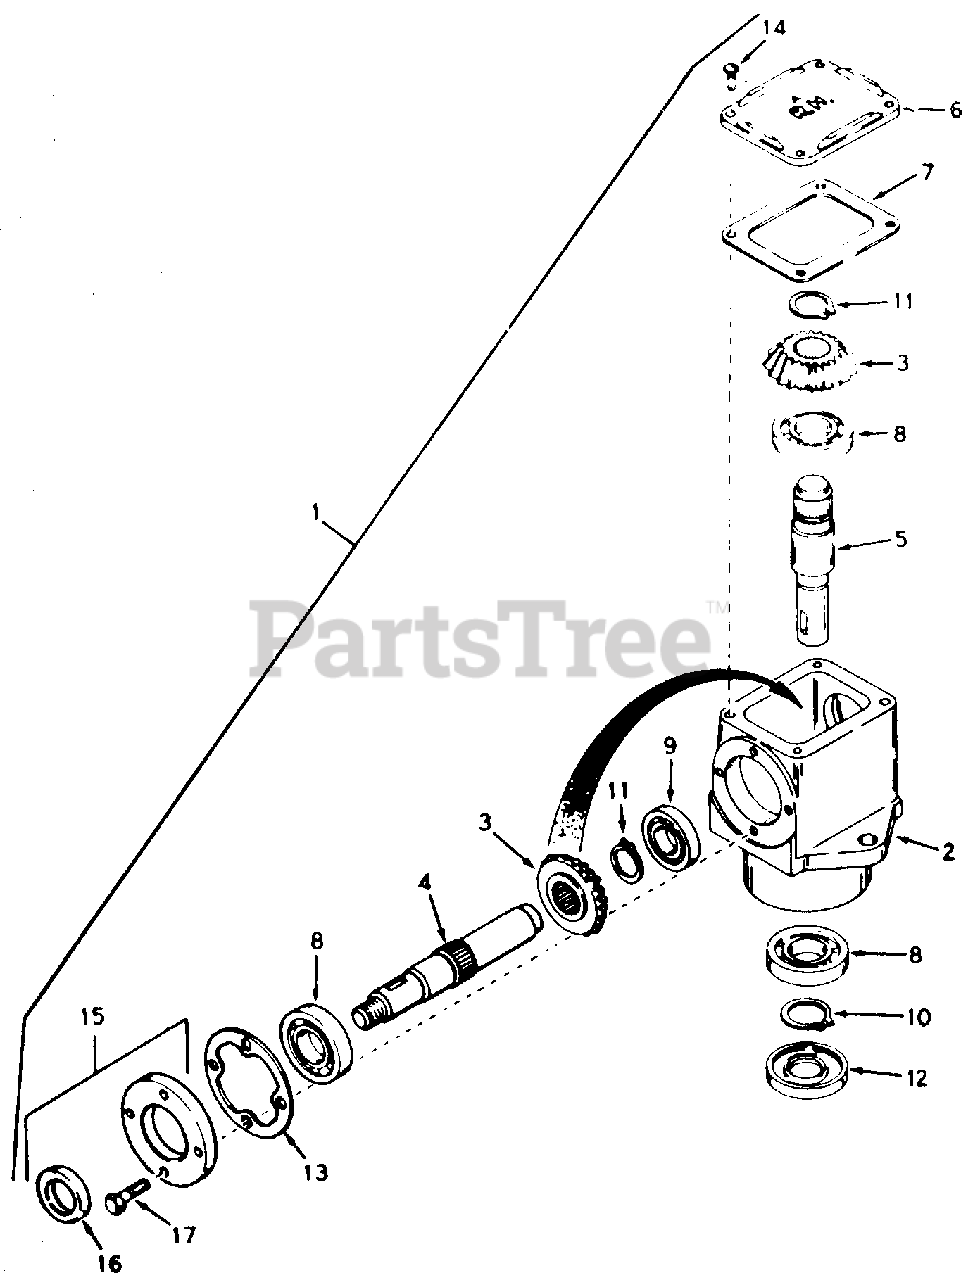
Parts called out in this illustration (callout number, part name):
1	Head Ass'y. R.H.
2	Housi ng, Right Angle Drive
3	Gear, Miter
4	Shaft, Input
5	Shaft, Output
6	Cover, Right Hand
7	Gasket, Cover
8	Bearing, Ball
9	Bearing, Ball
10	Ring, Snap
11	Ring, Snap
12	Seal, Oil
13	Gasket, Cap
14	Screw, Rd. Hd. Self Tap., 10-24 x 1/2
15	Cap & Seal Ass'y., Retainer
16	Seal, Oil
17	Screw, Hex Hd. 1/4-20 x 718
